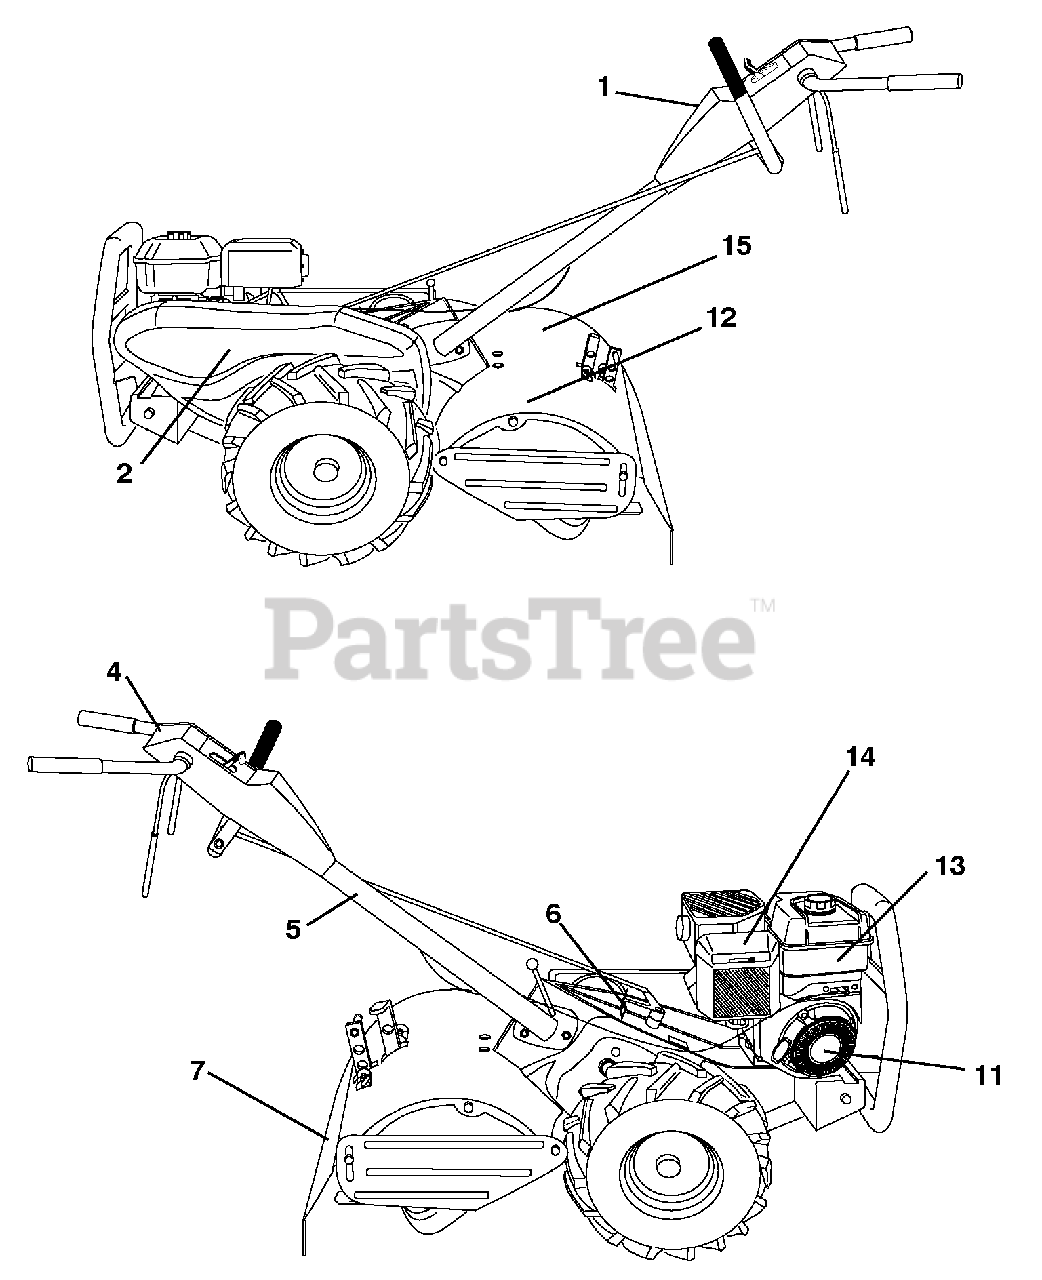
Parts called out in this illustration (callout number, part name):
1	Decal, CNTRL PNL
2	Decal, Decal, Blt Grd
4	Decal, Instruction, Tilling
5	Decal, Hand Placement
6	Decal, Shift Indicator
7	Decal, caution
11	Decal, Rewind
12	Decal Tine Direction Front
13	Decal, B&S Tank
14	Decal, B&S Air Cleaner
15	Decal, Tine Direction Rear
15	Manual, Operator's (E&F)
15	Manual, Parts (E&F)
